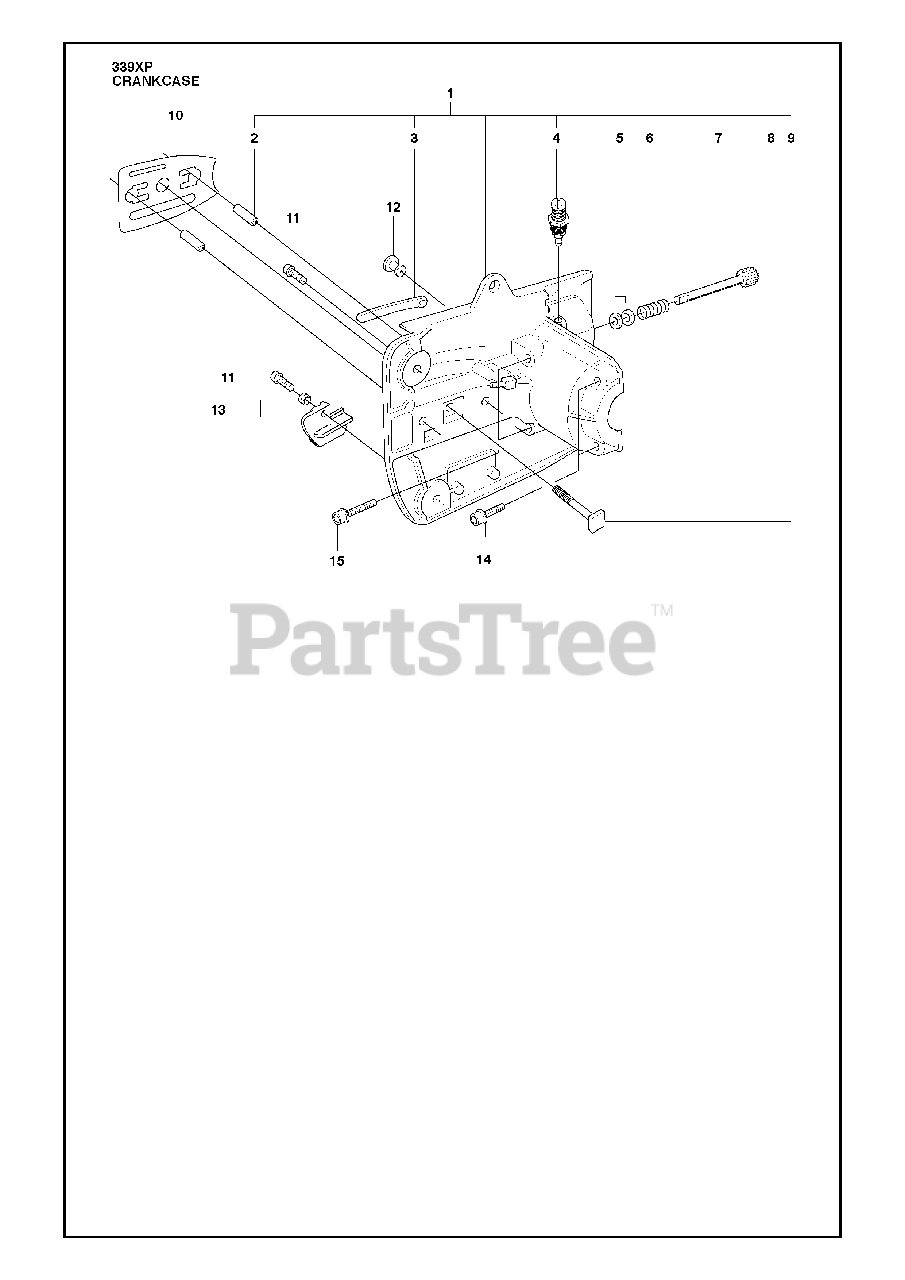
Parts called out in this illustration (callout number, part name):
2	GUIDE BAR LOCATING PIN
4	INSERT OIL PUMP
5	WASHER 5.1X8.5
7	PUMP PISTON
10	CHAIN GUIDE PLATE
13	CHAIN CATCHER
